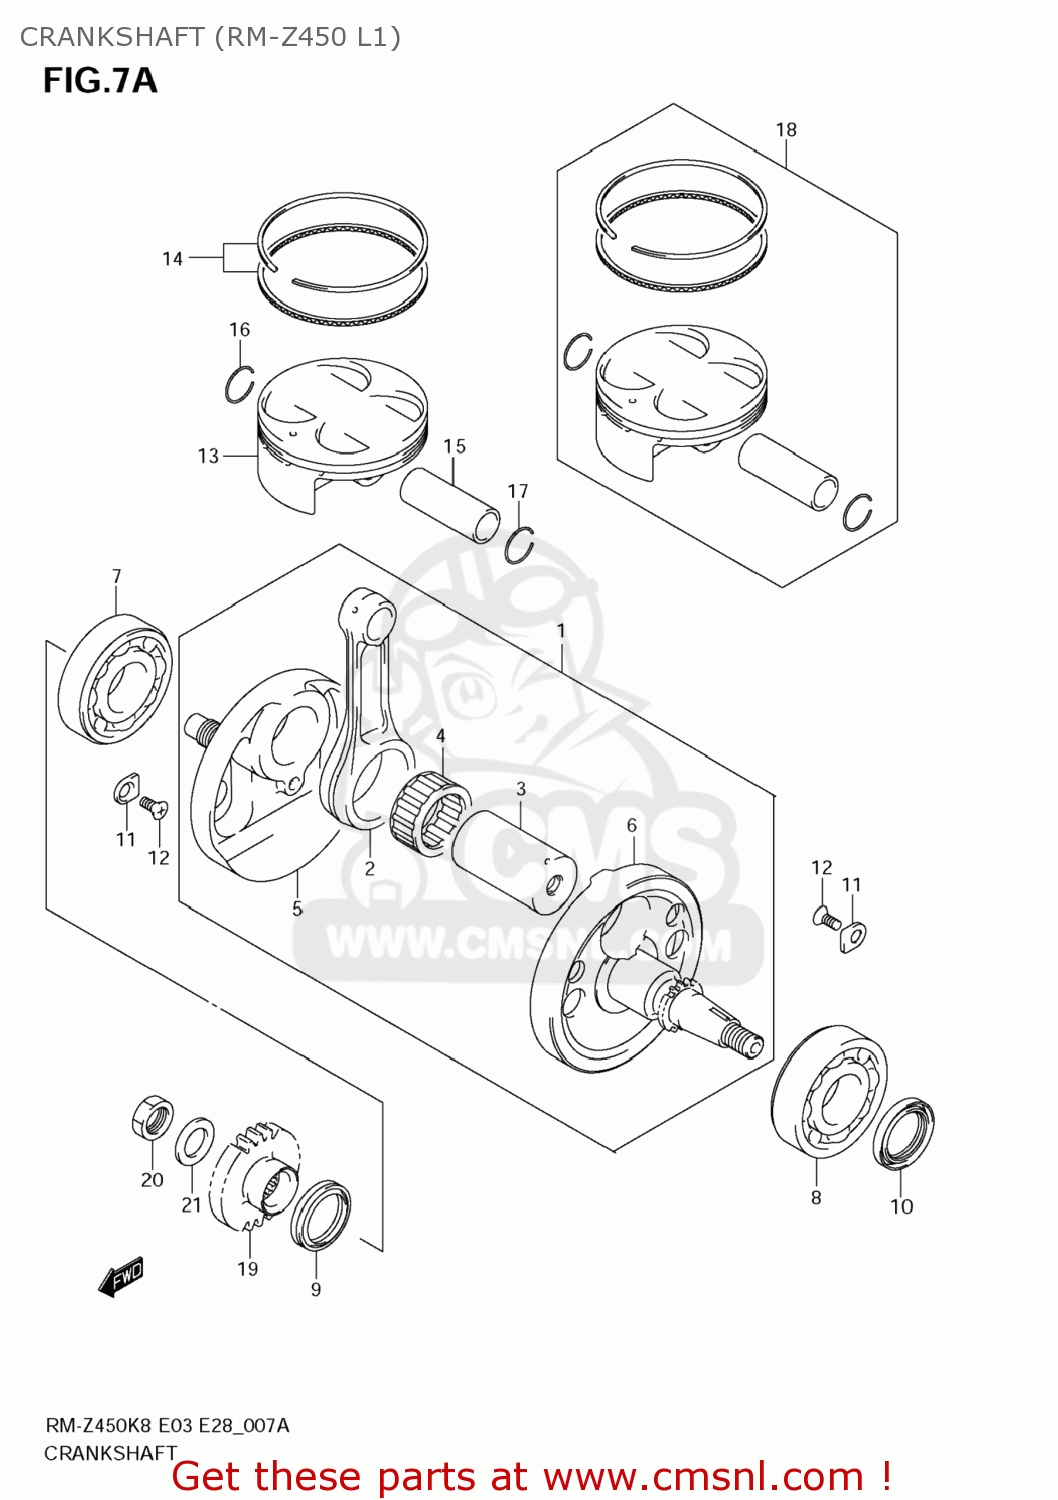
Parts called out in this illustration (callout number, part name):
1	CRANKSHAFT ASS
2	CONNECTING ROD ASSY
3	PIN,CRANK
4	BEARING(34X42X20)
5	CRANKSHAFT,R
6	CRANKSHAFT,L
7	BEARING(30X72X19)
8	BEARING(32X75X20)
9	SEAL,OIL(30X40X7)
10	SEAL,OIL(32X47X6)
11	RETAINER,COUNTER BEARING,R
12	SCREW(6X12)
13	PISTON
14	RING SET,PISTON
15	PIN,PISTON
16	RING,SNAP
17	CIRCLIP
18	PISTON KIT
19	GEAR,PRIMARY DRIVE
20	NUT
21	WASHER
